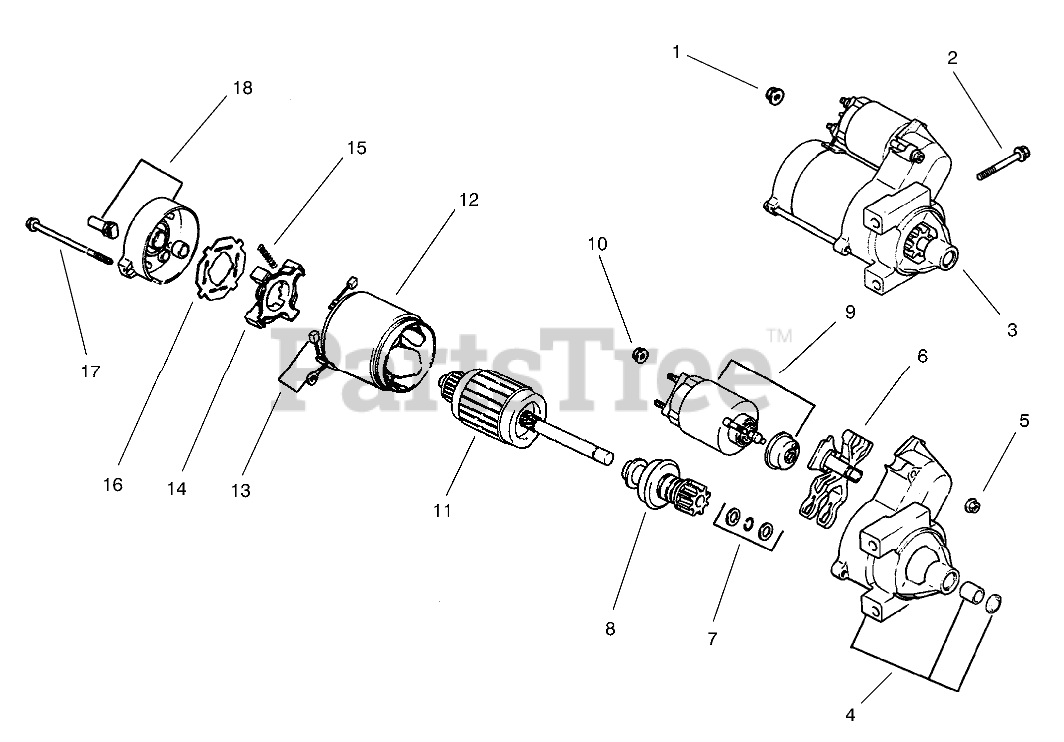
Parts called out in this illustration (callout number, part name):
1	Nut
2	Scew
3	Starter, solenoid shift assembly (Incl. 4-18)
4	Cap-Drive End
5	Nut
6	Lever Starter Drive
7	Washer
8	Drive Pinion
9	Solenoid
10	Nut
11	Armature-Starter
12	Frame
13	Kit, brush & spring (Includes 15)
14	Holder-Brush
15	Spring Brush
16	Insulator
17	Bolt
18	Commutator-End Cap
